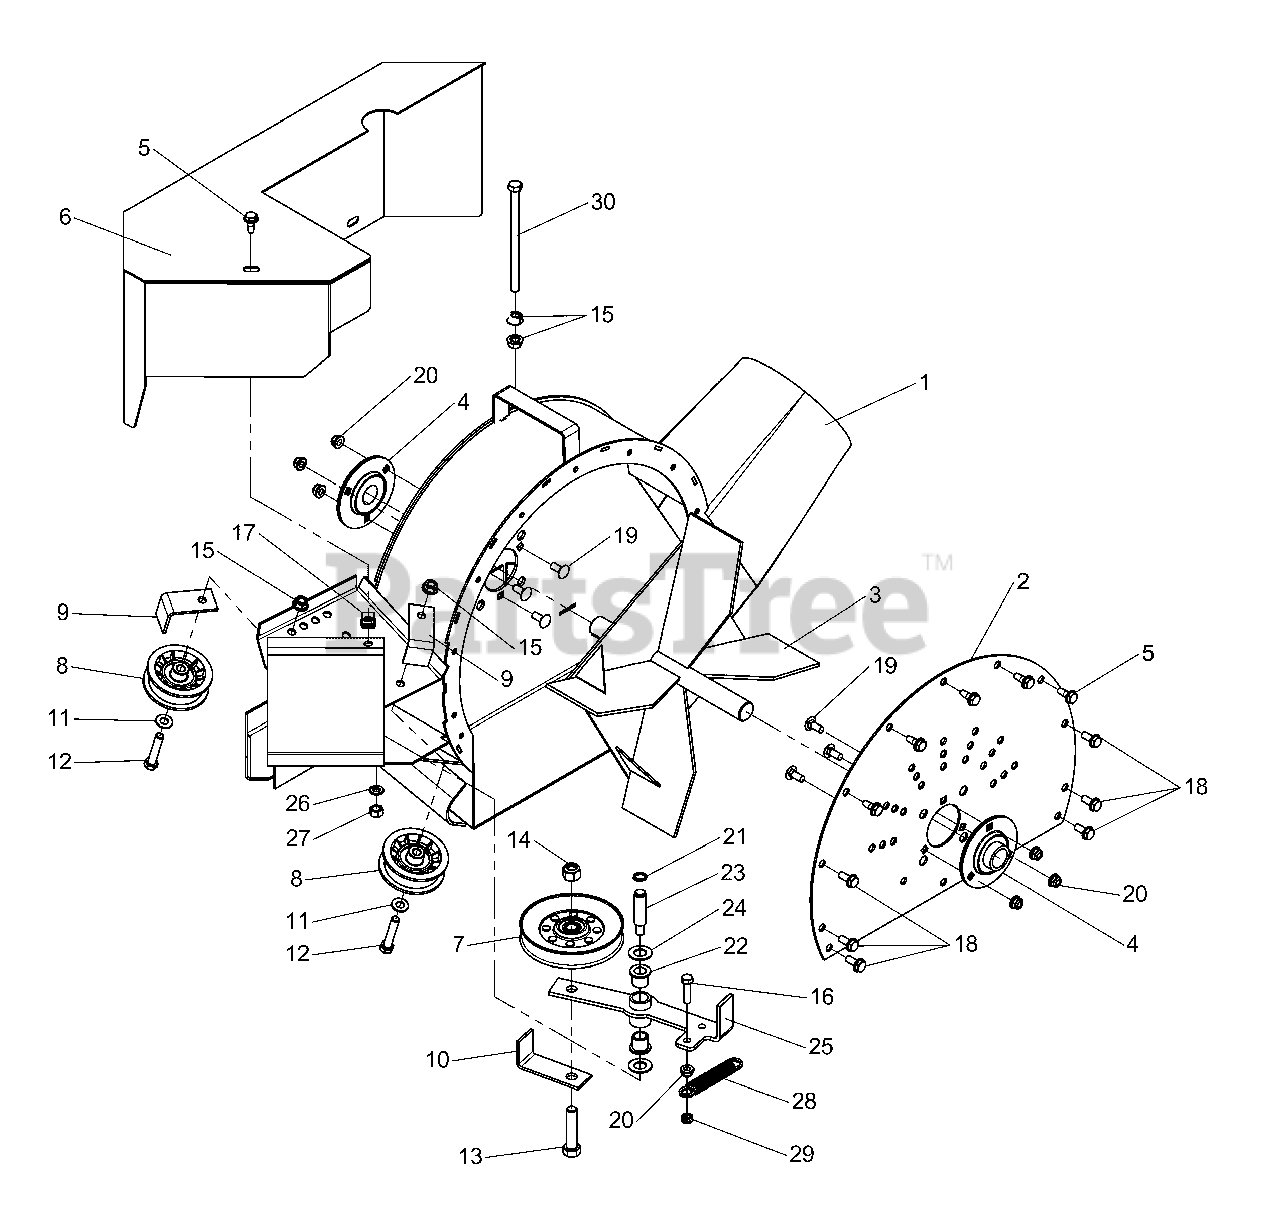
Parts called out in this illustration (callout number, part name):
1	BLOWER HOUSING
2	BACK PLATE
3	BLOWER IMPELLER
4	BEARING, FLANGE, 1" Bore
5	BOLT, 5/16-18 x 3/4" Self Tap
7	PULLEY, IDLER V-NOTCH, 5"
8	IDLER PULLEY ASSEMBLY
9	BELT KEEPER
10	KEEPER, BELT TENSIONER
11	WASHER 3/8" SAE
12	BOLT, 3/8-16 x 2
13	BOLT, 1/2-13 x 2-1/4
14	NUT, 1/2-13 Hex Nylon Lock
15	NUT, 3/8-16 Hex Large Serrated Flange
16	BOLT, 5/16-18 x 1-1/4
17	U-CLIP, 5/16-18
18	BOLT, 5/16-18 x 3/4" Self Lock
19	CARRIAGE BOLT, 5/16-18 x 3/4
20	NUT, 5/16-18 Hex Nylock Flange
21	RETAINING RING, 1/2"
22	FLANGE BEARING, 9/16"
23	IDLER STUD
24	FLAT WASHER, 9/16" Narrow
25	IDLER ARM
26	WASHER, 3/8 Lock
27	NUT, 3/8-24 Hex
28	SPRING, Extension
29	NUT, 5/16-18 Hex Center Lock
30	BOLT, 3/8-16 x 6" GD5
